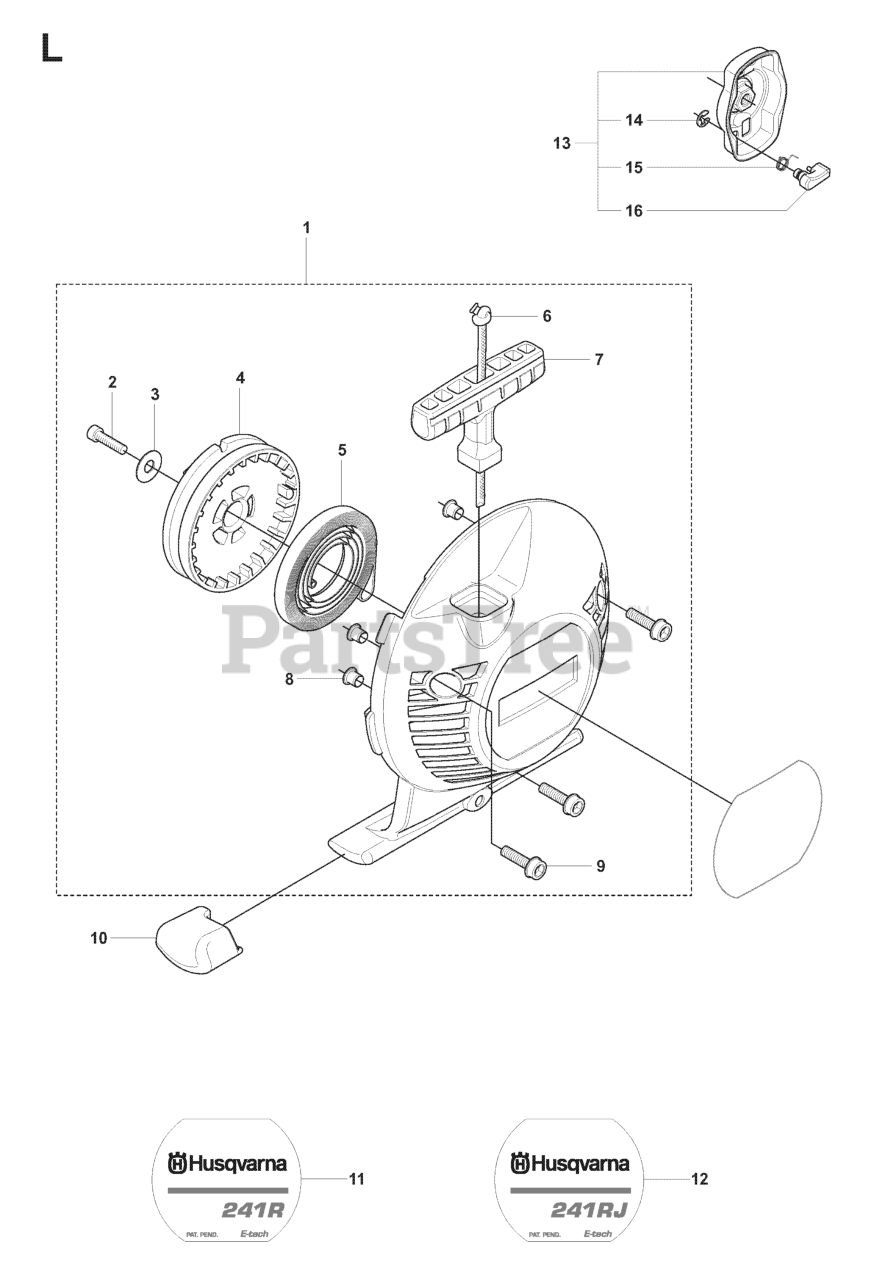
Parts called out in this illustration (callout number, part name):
1	STARTER COMPL.
3	WASHER
4	%STARTER PULLEY
5	STARTER SPRING
6	STARTER ROPE
7	STARTER HANDLE
9	SCREW IHSCFM
13	PAWL
16	STARTER PAWL
